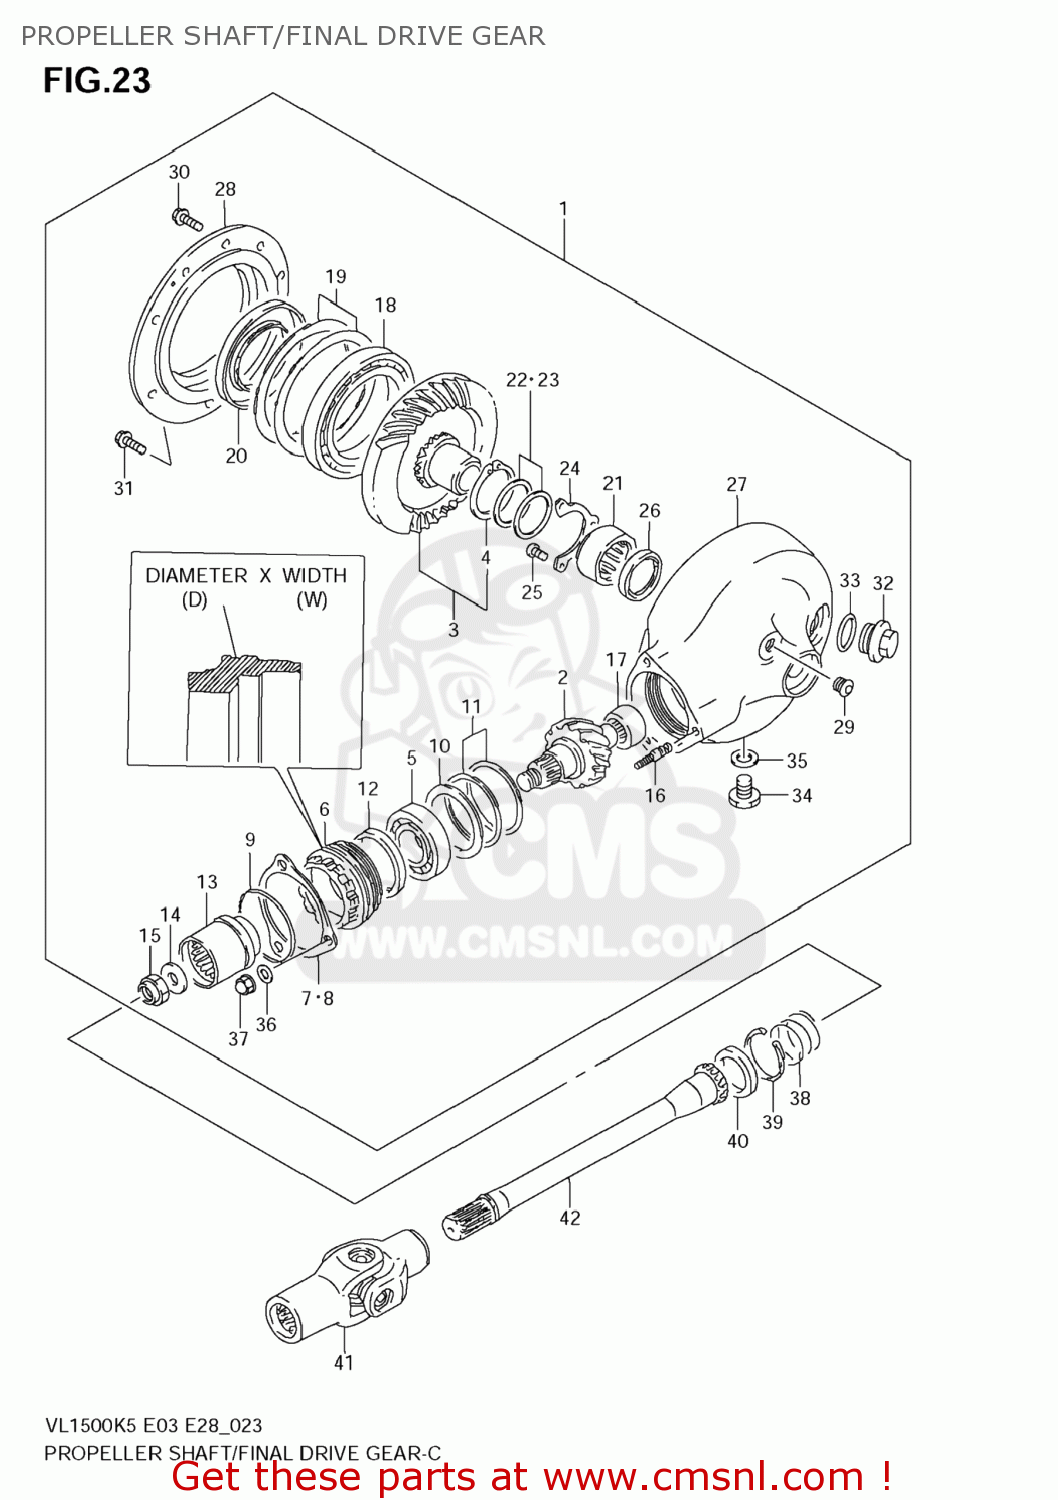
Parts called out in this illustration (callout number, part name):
1	GEAR & CASE SET,FINAL BEVEL
2	GEAR,FINAL DRIVE BEVEL
3	GEAR,FINAL DRIVEN BEVEL
4	.CIRCLIP
5	BEARING(28X68X18)
6	STOPPER,FINAL DRIVE BEARING
7	PLATE,BEARING STOPPER
8	PLATE,BEARING STOPPER
9	O RING(D:3.1,ID:63.9)
10	WASHER(54X68X1.5)
11	SHIM SET,FINAL DRIVE GEAR
12	SEAL,OIL
13	COUPLING,FINAL DRIVE GEAR
14	WASHER(16X29X4)
15	NUT
16	BOLT
17	BEARING(20X34X18)
18	BEARING(85X130X14)
19	SHIM SET,FINAL DRIVEN GEAR
20	SEAL,OIL(70X110X14.7)
21	BEARING(35X48X23.7)
22	WASHER(35X46X0.95)
23	SHIM SET,FINAL DRIVEN GEAR
24	RETAINER,FINAL DRIVEN GEAR BRG
25	SCREW
26	SEAL,OIL(35X43X5)
27	CASE,FINAL GEAR
28	CASE,FINAL GEAR BEARING
29	PLUG,16X8
30	BOLT
31	BOLT
32	PLUG,30X9
33	O RING(D:3.1,ID:26.4)
34	PLUG(MAGNETO)
35	GASKET(13.8X18.8X4.8) (NAS)
36	WASHER
37	NUT
38	SPRING
39	CIRCLIP
40	SEAL,OIL(30X40.5X5.5)
41	YOKE COMP,UNIVERSAL JOINT
42	SHAFT,PROPELLER
